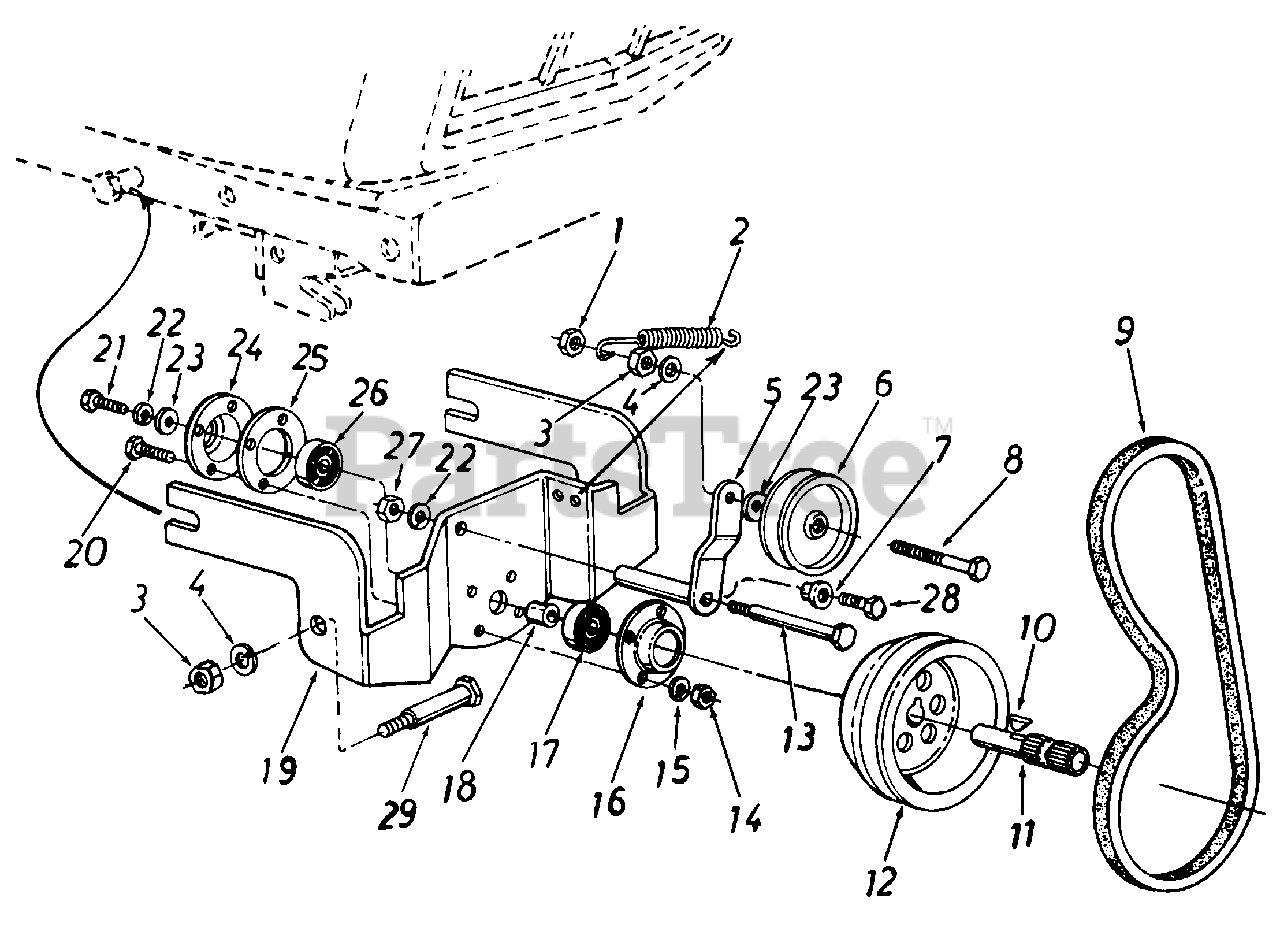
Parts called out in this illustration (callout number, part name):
1	Hex Cent. L. Jam Nut 3/8-16 Thd.
2	Extension Spring .54" x 5.25" Lg.
3	Hex iam Nut 3/8-16 Thd.
4	L.-Wash. 3/8" I.D.*
5	Idler Brk't. 1.5 x 4.5" Lg. (418)
6	Fl.-ldler w/Flanges 2.25" O.D. (418)
7	Shld. Spacer.680 Dia. x .170 (418)
8	Hex Bolt 3/8-16 x 2 00" Lg. *
9	"V"-Belt 1/2 x 37.0" Lg. (418)
10	#9 Hi-Pro Key 3/16 x 3/4" Dia.
11	Spline Shaft 3.94" Lg.
12	5/8" Pulley .790" I.D. x 7.0" O.D. (418)
13	Shoulder Bolt .498" Dia. x 2.0" Lg. (419)
14	Hex Nut 5/16-24 Thd.*
15	L.-Wash. 5/16" I.D.*
16	Bearing Shield (Incl. Ref. 17)
17	Ball Bearing .787" I.D. x 1.85" O.D.
18	Spacer 1.0" O.D. x .790" I.D. x.350" Lg.
19	P.T.O. Support Bracket
20	HexBolt 5/16-24 x 1.00" Lg. *
21	Hex L.-Bolt 3/8-24 x 1.00" Lg.
22	L.-Wash. 3/8" I.D.*
23	Bell.-Wash. .400" I.D. x 1.25" O.D.
24	Open Bearing Housing 1.85" I.D. (Incl. Ref. 26)
25	Reinforcement Plate
26	Ball Bearing .787" I.D. x 1.85"
27	Hex Jam Nut 3/8-16 Thd.
28	Hex Bolt 3/8-16 x 1.0" Lg. (Grade 5)
29	Shld. Bolt .498" Dia.
